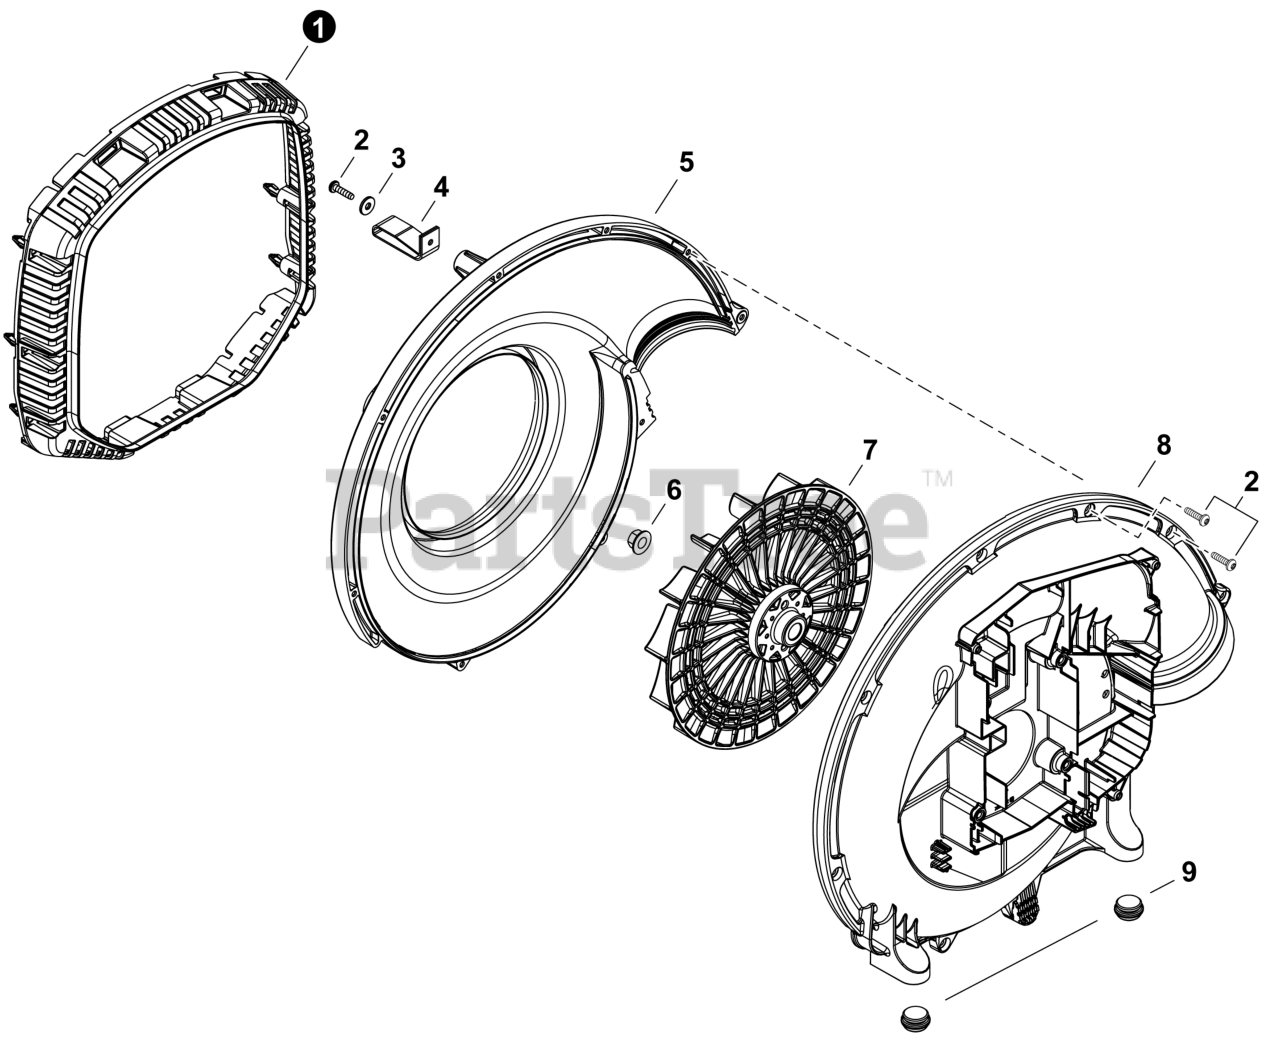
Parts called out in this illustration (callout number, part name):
1	GUARD, DEBRIS
2	BOLT, TORX 5x20
3	WASHER 5.5x16x2T
4	STRAP, SAFETY
5	COVER, FAN
6	NUT, FLANGE 10x1.25
7	FAN, BLOWER
8	CASE, FAN
9	CUSHION
